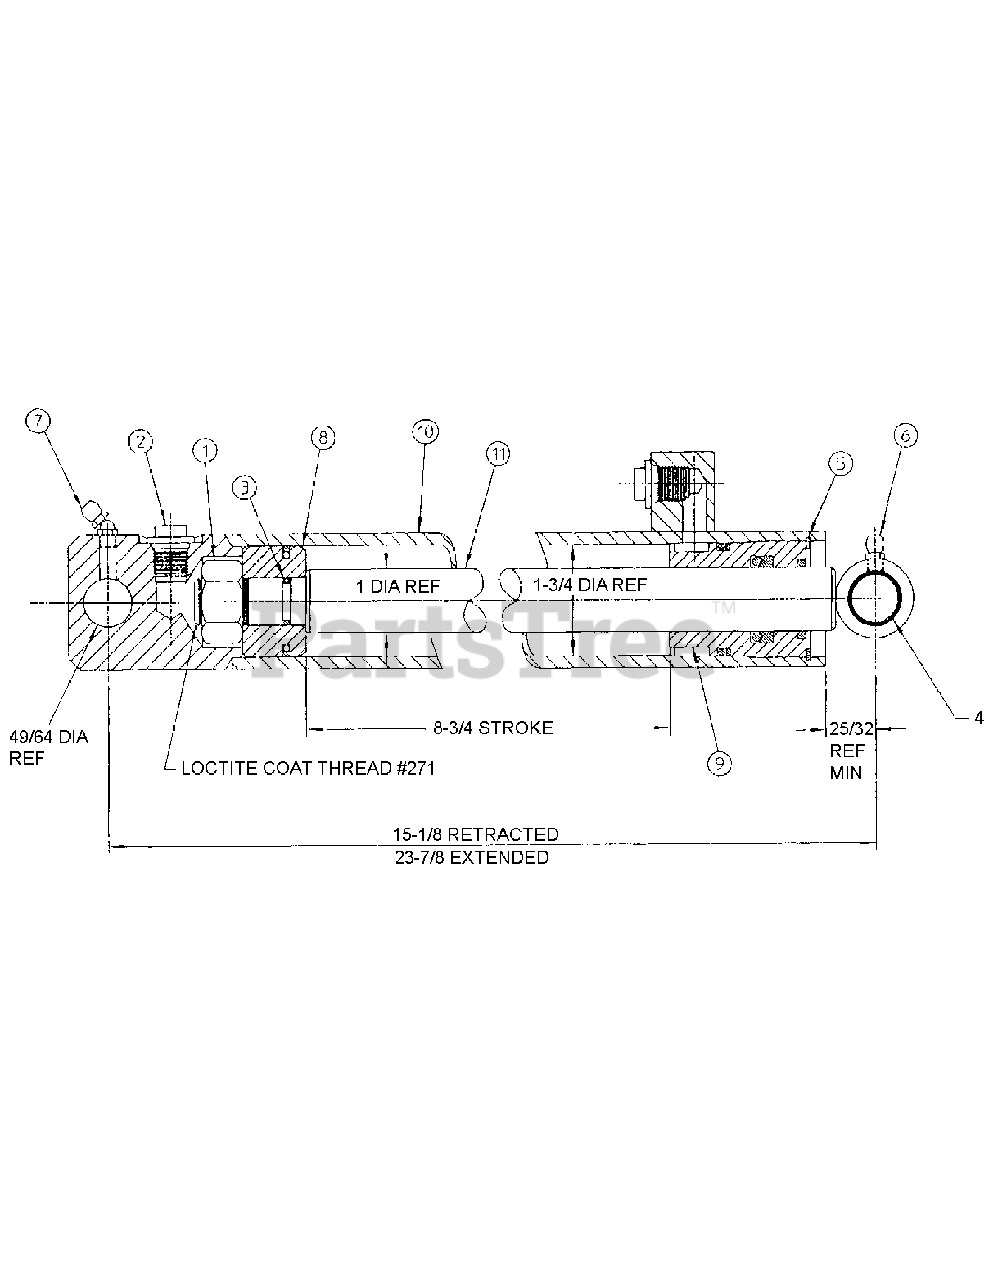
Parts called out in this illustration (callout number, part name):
1	NUT, 3/4'' NF LOCK
3	O-RING
4	BRONZE BEARING 7/8''OD X 3/4''ID X 1'' LONG
5	RETAINING RING
6	GREASE FITTING, 1/4-8 SELF TAPPING
7	GREASE FITTING, 1/4-8 SELF TAPPING X 45 DEGREE
8	PISTON ASSEMBLY WITH O-RING
9	GLAND WITH O-RING, BACK-UP RING, ETC.
10	CYLINDER TUBE WELDMENT
11	PISTON ROD WELDMENT WITH BRONZE BEARINGS
